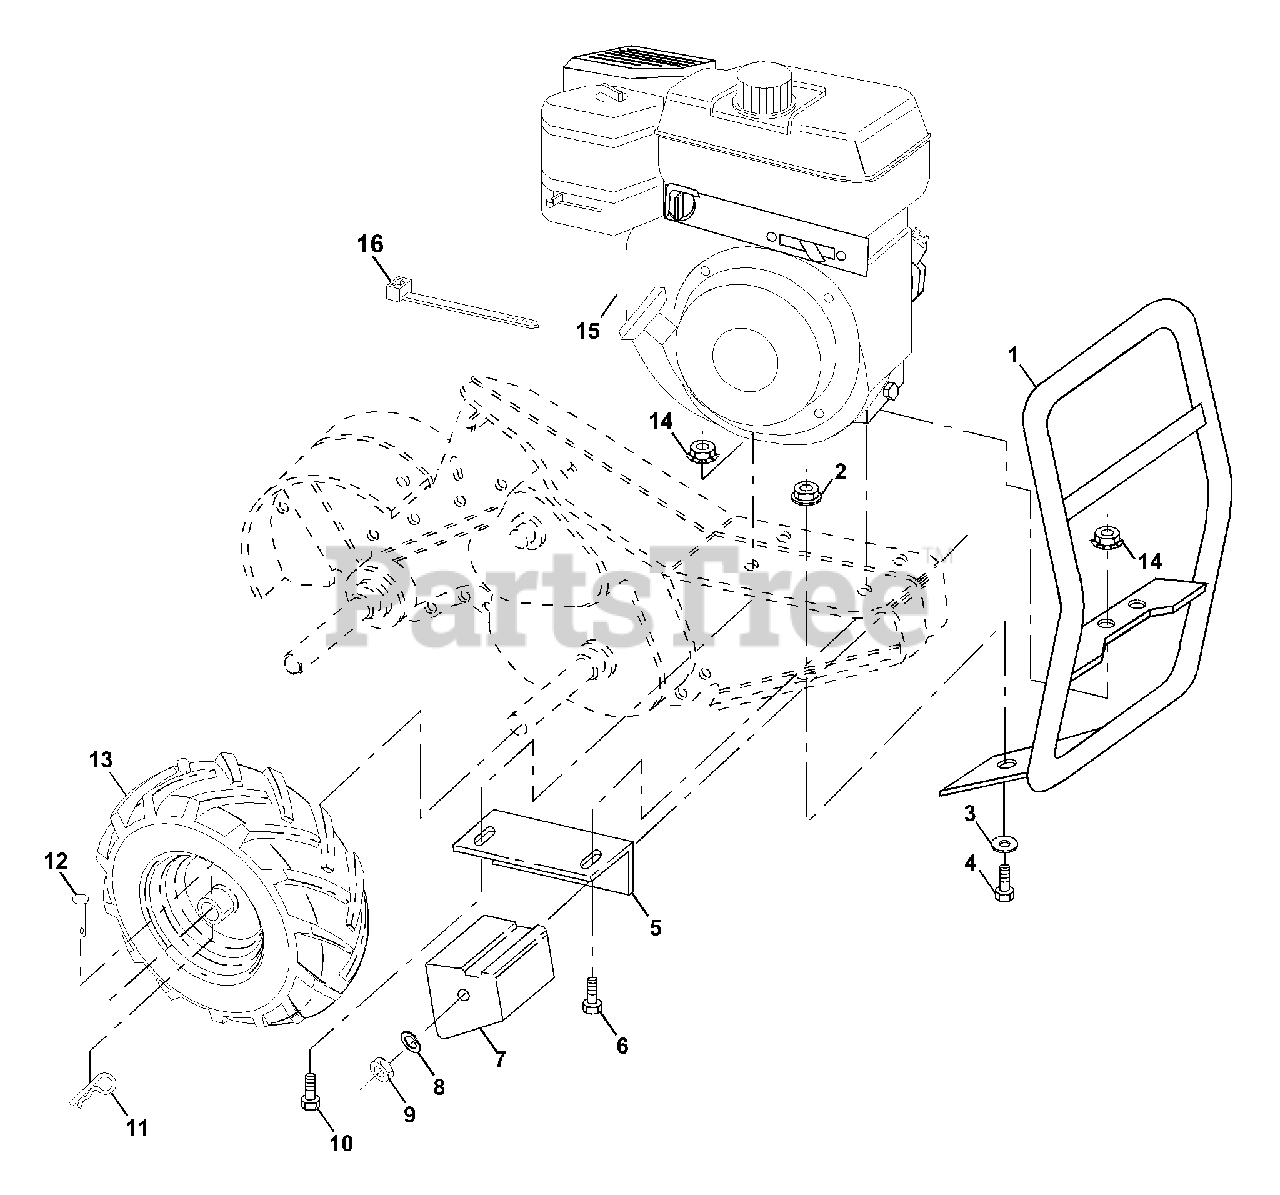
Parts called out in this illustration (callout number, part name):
1	Bumper
2	Locknut, Hex, Flange 5/16-18
3	Washer 11/32 x 11/16 x 16 Ga.
4	Bolt, Hex 5/16-18 x 3/4
5	Bracket, Reinforcement
6	Bolt, Hex 5/16-18 x 2
7	Counter Weight, R.H.
8	Washer, Lock 3/8
9	Nut, Hex 3/8-16
10	Bolt, Hex 5/16-18 x 1-1/2
11	Clip, Hairpin
12	Rivet, Drilled
13	Tire
13	Rim
13	Tire Valve
14	Nut, Keps 5/16-18
16	Tie Cable
